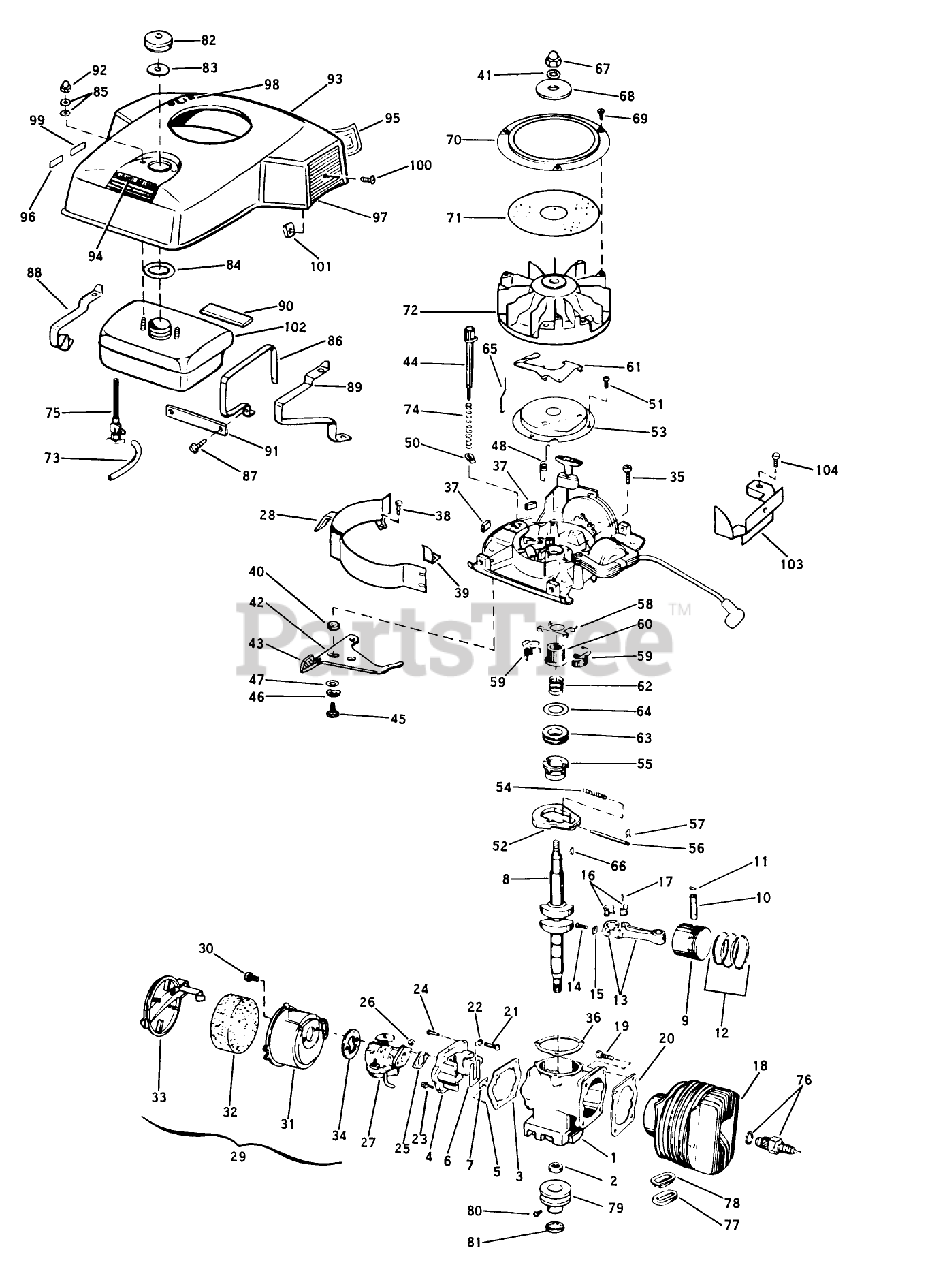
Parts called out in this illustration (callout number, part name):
7	PLATE-BACKUP, REED
11	RING-RETAINING
16	LINER ASM
20	GASKET S
23	SCREW S
24	SCREW S
25	GASKET S
26	STOP NUT
30	SCREW S
32	AIR FIL.ELEM S
36	GASKET S
39	Stiffener-Baffle
40	Washer-Vari-Speed
51	SCREW S
52	FLYWEIGHT S
53	DUST COVER S
54	SPARK ADV. SPRING S
55	SPARK ADV. S
56	PIN,SPARK ADV. S
57	SPARK ADJ. SPRING
60	COLLAR S
61	LEVER-GOVERNOR S
62	SPRING S
63	THRUST COLLAR S
70	Ring-Flywhl. Scrn.
74	SPRING S
75	VALVE&SCREEN SM
76	Spark Plug
77	GASKET S
86	Strap Screw Assy.
88	Bracket-L.H.
89	Bracket-R.H.
91	Tie Strap
92	PALNUT S
94	Decal-Instruction
98	Decal-On-Off
101	Nut-Shroud Mounting
102	Gas Tank
103	Baffle-R.H.
104	SCREW S
